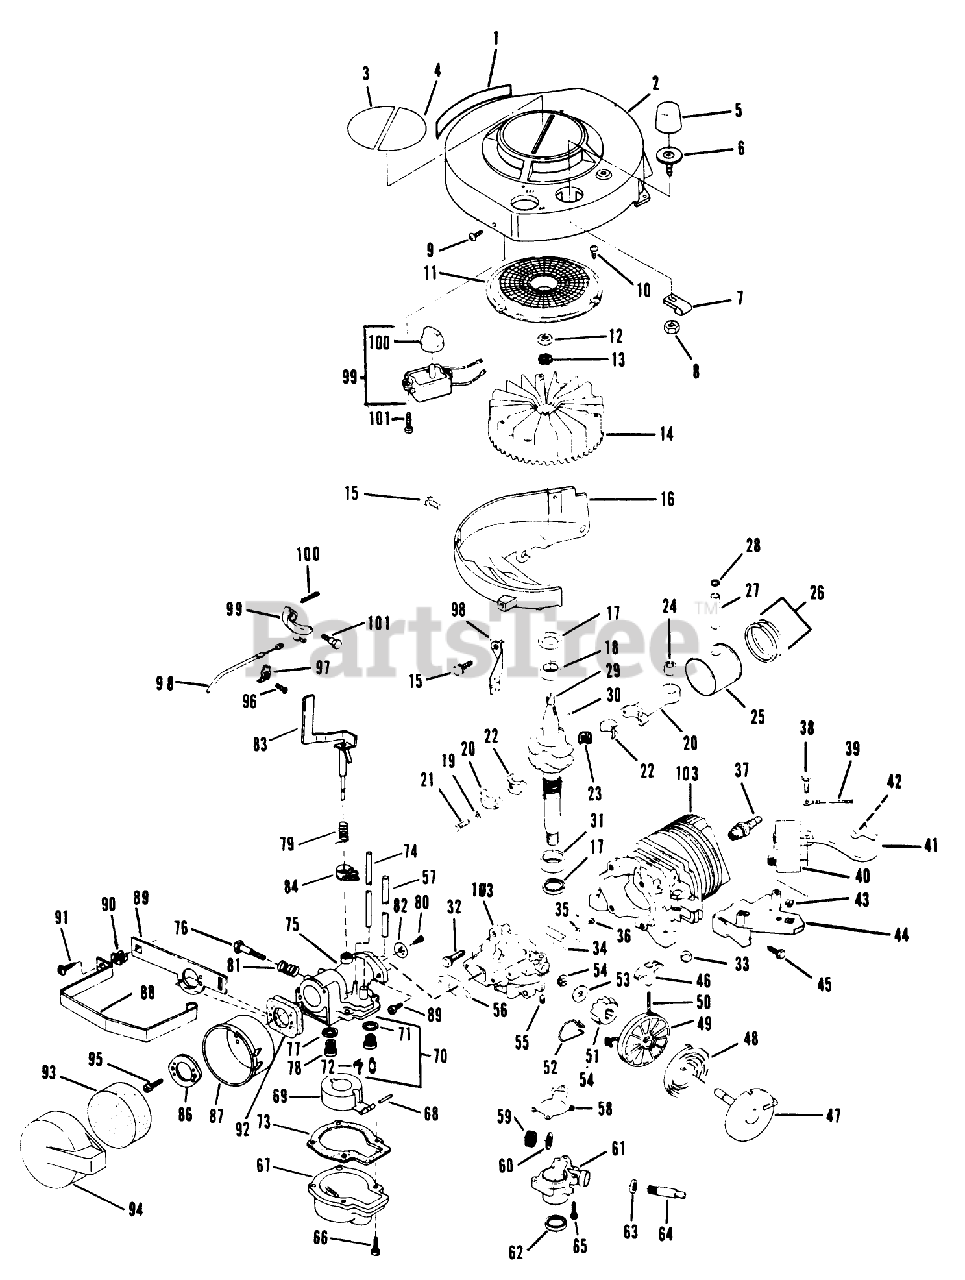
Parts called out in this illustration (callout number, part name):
8	LOCKNUT S
9	SCREW F
10	SCREW F
12	NUT
15	SCREW-SEMS
18	BEARING V
21	SCREW
22	LINER ASM
24	BEARING AY F
28	RING-RETAINING
30	KEY
31	BEARING S
32	SCREW S
33	PLUG-CORE VF
35	PLATE-BACKUP, REED
41	HT LEAD&COVER XEV
43	NUT-CLIP
44	BRACKET S
46	HANDLE STARTER S
48	SPRING S
52	SPRING F
53	WASHER S
55	SET SCREW
56	GASKET CARB S
58	GASKET S
59	GEAR, DR SHAFT S
60	THRUST WASHER
63	SEAL S
71	WASHER
74	TUBING PRIMER S
76	SCREW S
77	WASHER
78	PLUG S
80	SCREW F
81	SPRING S
84	CLAMP-SPR ADJ S
85	SCREW S
86	WASHER S
88	STRAP S
90	NUT-CLIP
91	SCREW S
92	GASKET S
93	AIR FIL.ELEM S
95	SCREW S
97	CLIP S
99	LEVER LOCKOUT S
101	BOLT S
